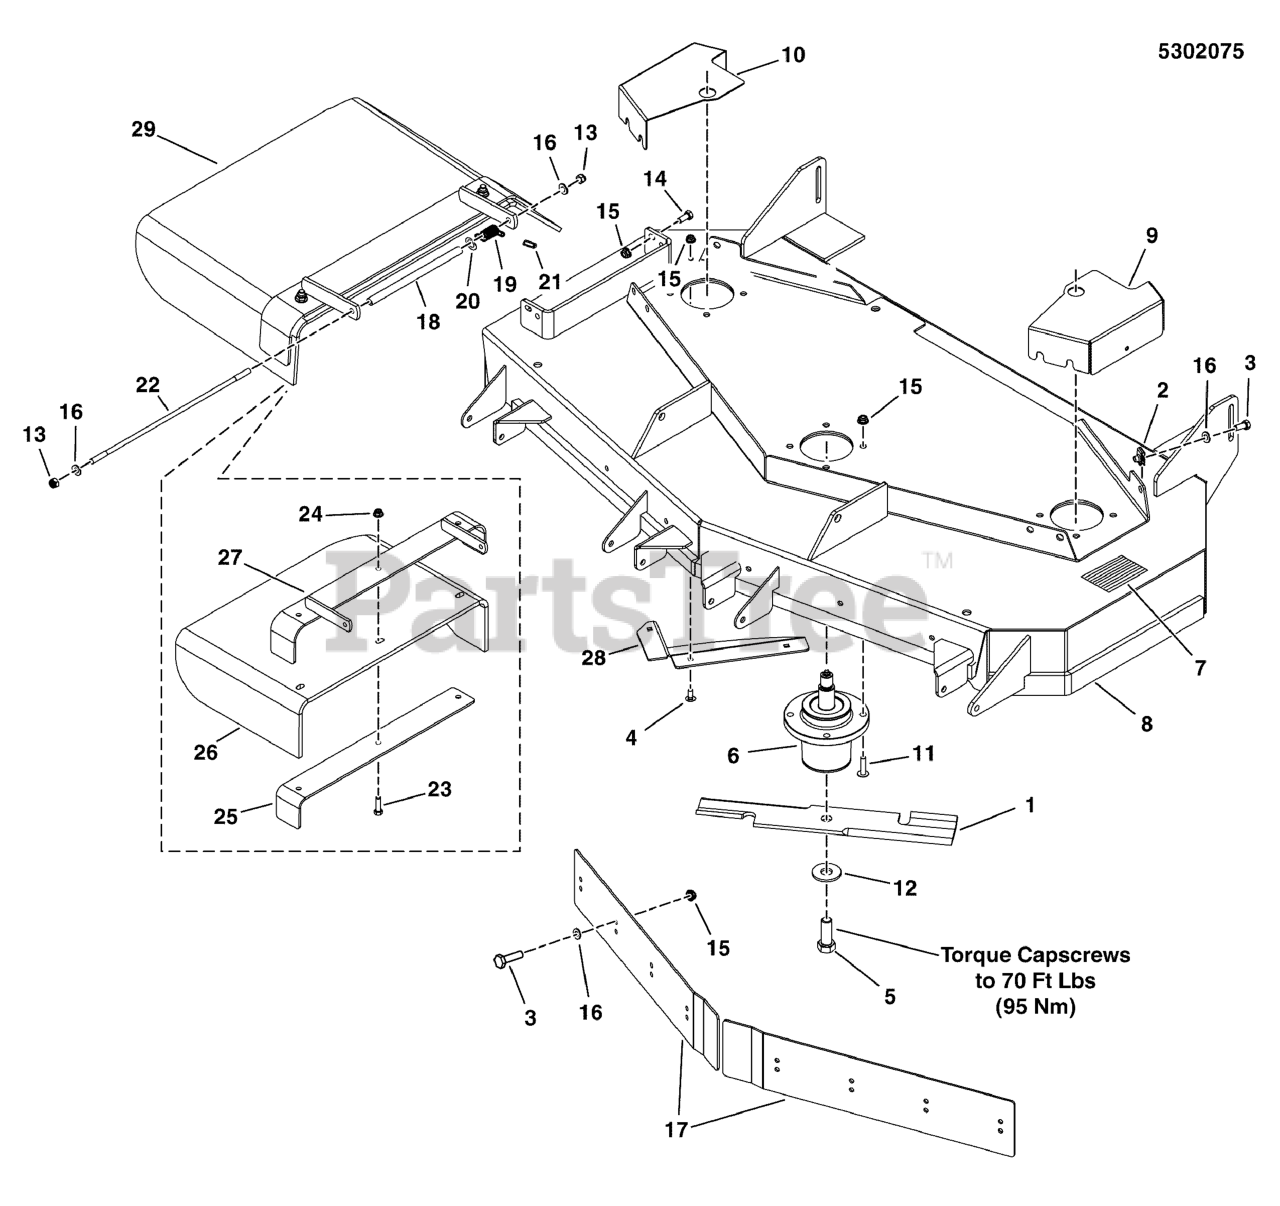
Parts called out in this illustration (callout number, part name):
1	BLADE, 18, SET OF THREE
2	BODY CLIP, 5/16-18-7GA MATERIAL
3	BOLT, 5/16-18 X 3/4 GD5
4	BOLT, 5/16-18 X 3/4, CARRIAGE
5	BOLT, 5/8-11 X 1-3/4 GD8
6	ASSM, SPINDLE, LOW PROFILE
7	SAFETY WALK, 4.00 X 7.50
8	DECK SHELL W/ DECALS, 52SB, S175X
9	GUARD, 52" DECK, IS2000 - LH - RED
10	GUARD, 52" DECK, IS2000 - RH - RED
11	BOLT, 5/16-18 X 1 1/4 FLANGE
12	WASHER, 5/8 GRADE 8, YZ
13	NUT, 5/16-18 HEX NYLON LOCK
14	BOLT, 5/16-18 X 1-1/4 GD5 YZ
15	NUT, 5/16-18 HEX NYLOCK FLANGE
16	WASHER, 5/16" SAE
17	BAFFLES. FRONT DISCHARGE, 52 YAN - BLK
18	TUBE, 1/2 X 3/8 BLACK POLY, 8.00 LG
19	SPRING, TORSION
20	WASHER, 5/16 FENBER
21	CAP, PROTECTOR, .120 ID
22	ROB, 5/16 X 13.75,
23	BOLT, 3/8-16 X 1-1/2" GD5 CZ
24	NUT, 3/8-16 HEX NYLOCK FLANGE
25	SUPPORT,DISCHARGE CHUTE - BLK
26	CHUTE, DISCHARGE, RUBBER, 44/48/52
27	WELD, MOUNT, DISCHARGE CHUTE - BLK
28	WELD, DISCHARGE BAFFLE, 52" - BLK
29	KIT, DISCHARGE CHUTE, 44/48/52
